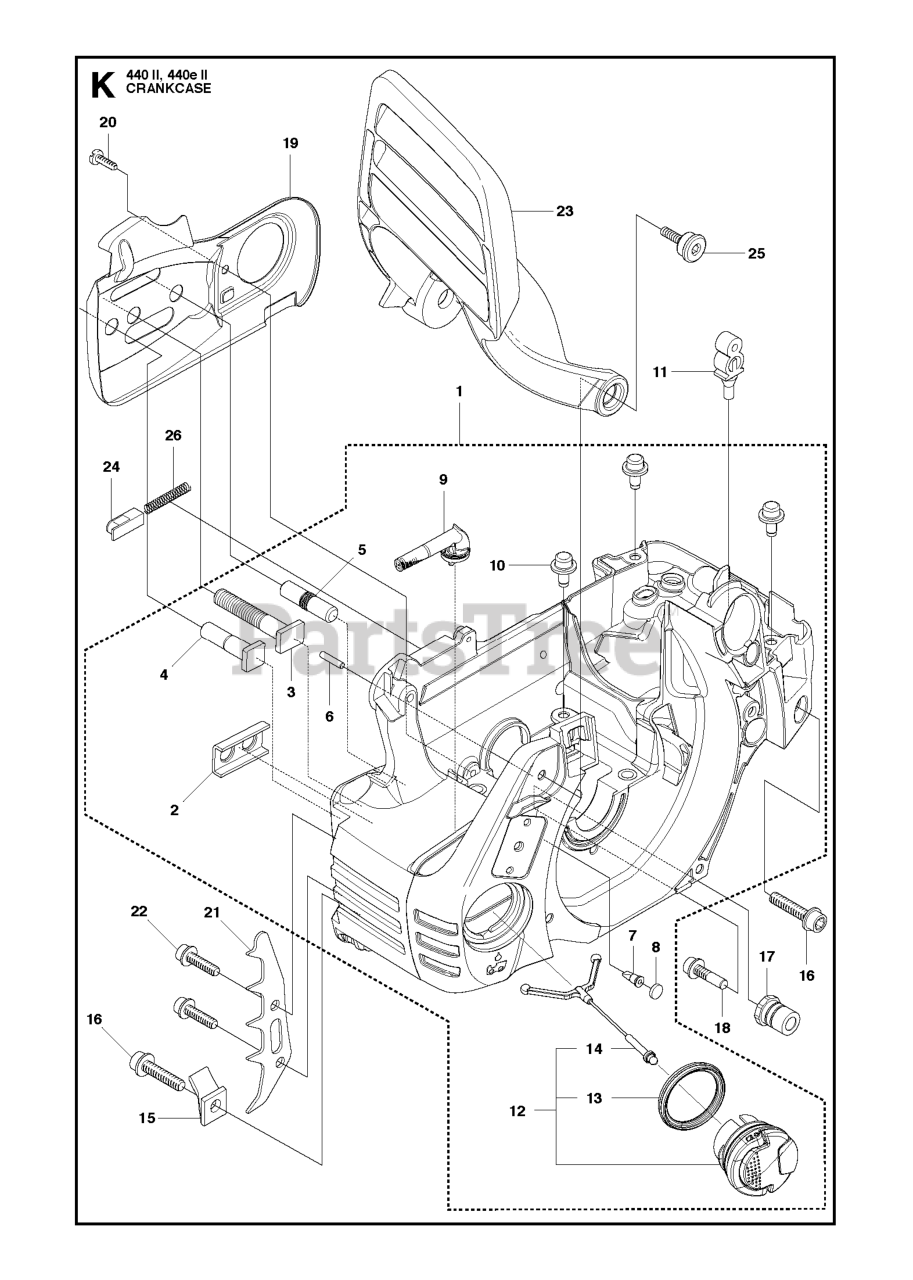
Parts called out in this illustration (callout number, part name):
1	CRANKCASE ASSY
2	STIFFENING PLATE
7	VALVE-CHECK (DUCKBILL)
8	PLUG
9	OIL SCREEN
11	SUPPORT
12	TANK CAP ASSY
13	SEALING
15	CHAIN CATCHER
17	LATERAL SUPPORT
18	SCREW IHSCFT
19	CHAIN GUIDE PLATE
21	SPIKE INNER
23	HAND GUARD
26	LOCK SPRING
